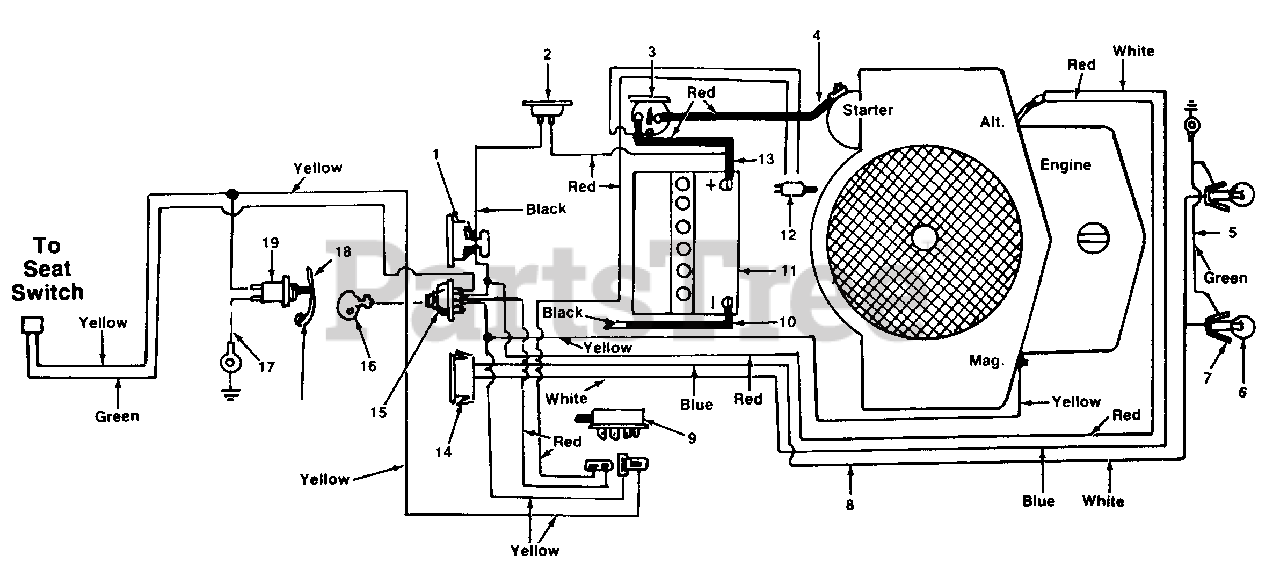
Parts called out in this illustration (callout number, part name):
1	Ammeter
2	Circuit Breaker
3	Solenoid
4	Wire
5	Ground Wire
6	Bulb
7	Socket
8	Wire Harness
9	Safety Switch
10	6 Ga. Black Wire
11	Battery 12V
12	Safety Switch
14	Light Switch
15	Ignition Switch
16	Ignition Key
17	Electric Wire
18	Spring Lever
19	Safety Switch
